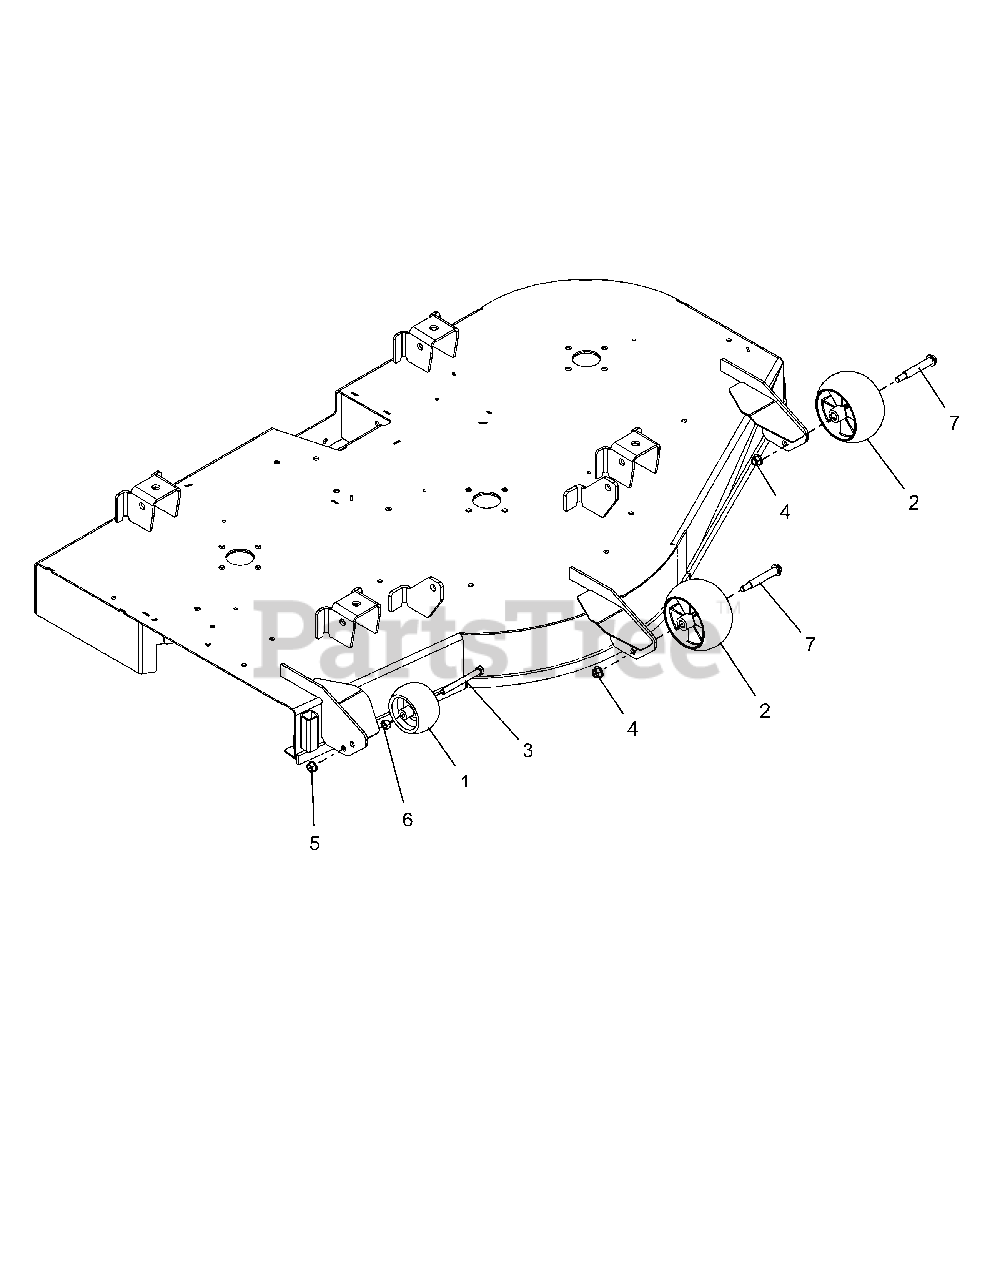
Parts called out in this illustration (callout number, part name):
2	ANTI-SCALP WHEEL - 5X OS
3	@BLT-HEX .38-16X3.50 GR5 YWZC
4	NUT,NYL-FLG .38-16 GF ZCC
5	NUT-LK-TOP-FLG .38-16 ZC120
6	@NUT-HEX .38-16 YWZC
7	BLT-SHLDR .38-16X2.50 HWH G5
